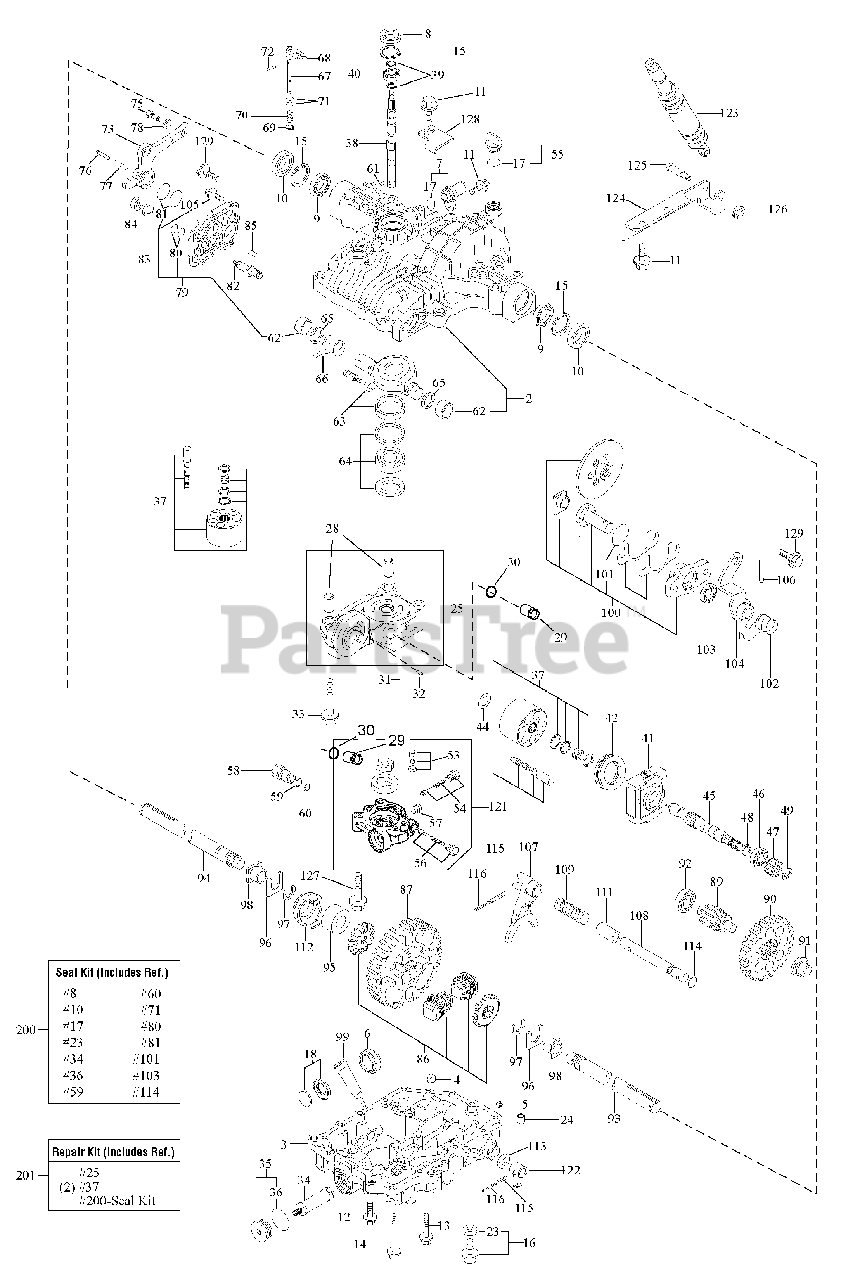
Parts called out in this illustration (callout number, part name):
2	*UPPER HOUSING
3	LOWER HOUSING
4	BORE PLUG 17
5	TAPER PLUG, 1/8, (K71E Only)
10	SEAL
11	SCREW, Tapping, 8 x 25
12	SCREW, Tapping
13	SCREW, Tapping, 8 x 45
14	BOLT, 8 x 75"
16	BOLT, 10 x 12
17	PACKING, P18
18	MAGNET COMPLETE
23	WASHER, Seal 10
24	PIPE, 13 x 11.3
25	*CENTER CASE, Complete
28	KNOCK PIN, 15.5 x 30
29	PLUG, 16 x 25
32	PIN, 3 x 9.8
33	BOLT, 10 x 75
34	FILTER
37	*CYLINDER BLOCK, Complete
40	BEARING, 6303
41	*HOUSING
44	WASHER, 18 x 31 x 1
45	*SHAFT MOTOR
46	BEARING 6004 SH2 U
48	SNAP RING, 20
49	RING, E15
53	*HOLDER, Seat
54	*VALVE, Implement Complete
55	CAP, Oil, 20
56	*VALVE, Charge Complete
61	PIN, 3.2 x 21
62	BEARING, 28 x 15
63	*SWASH PLATE COMPLETE
64	*BEARING COMPLETE
65	*WASHER
66	*SPRING (N/C)
67	*SHAFT (BYPASS)
68	*LEVER (BYPASS)
71	O-RING, 1A P10A
72	PIN, 3.0A*20
73	CONTROL LEVER
76	PIN, 6.0A x 50
77	PIN, 3.5A x 50
79	SIDE COVER SET, (Includes Ref. Nos. 2, 80 & 81)
80	PACKING, P14
81	PACKING, P28
82	*FULCRUM, (ECCENT)
86	KIT, Diff Gear
87	*FINAL GEAR
89	*SHAFT, (F PINION)
90	*REDUCTION GEAR
93	AXLE SHAFT, Left
94	*AXLE SHAFT, Right
95	*COLLAR, (Diff. Lock)
96	THRUST WASHER
98	*BUSHING
102	SP, (RETURN)
103	SEAL, TC173007
104	*ARM, (BRAKE)
105	*BOLT
106	PIN, 6.0A x 4.0
107	*FORK, Differential Lock
108	SHAFT, Differential
109	SPRING, Differential Lock
111	COLLAR (STOP)
112	*SLIDER, (Diff. Lock)
115	PIN, 6.0A x 32
116	PIN, 3.5A x 32
122	ARM, Differential Lock
123	SHOCK ABSORBER
127	BOLT 8 x 45
128	*STOPPER, Brake
129	BOLT, 8 x 25
200	SEAL KIT, K71J
201	*KIT, Seal
